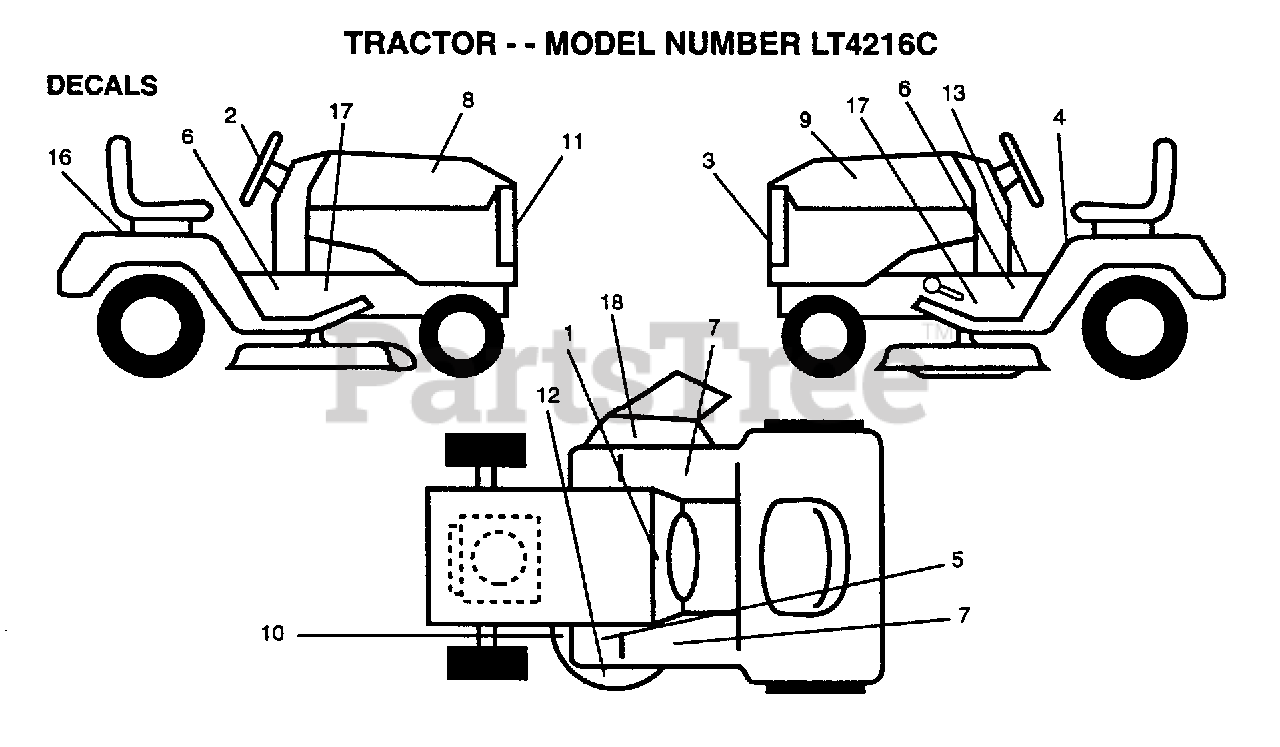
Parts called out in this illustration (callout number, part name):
1	DECAL INST OP DAS
2	DECAL.INST.WHL.ST
3	DECAL LOGO GRILLE
4	DECAL CAUT FEND
5	DECAL CLUT/BRAKE
6	DECAL CHASSIS KGR
7	FOOTREST PAD
8	DECAL.HD.RH.KGRO
9	DECAL.HOOD.LH.KGR
10	DECAL
11	DECAL.GRILLE.KGRO
12	DECAL DECK MULCH
13	DECAL BRAK PARK
16	DECAL FEND QUICK
18	DECAL DANGER CT/F
